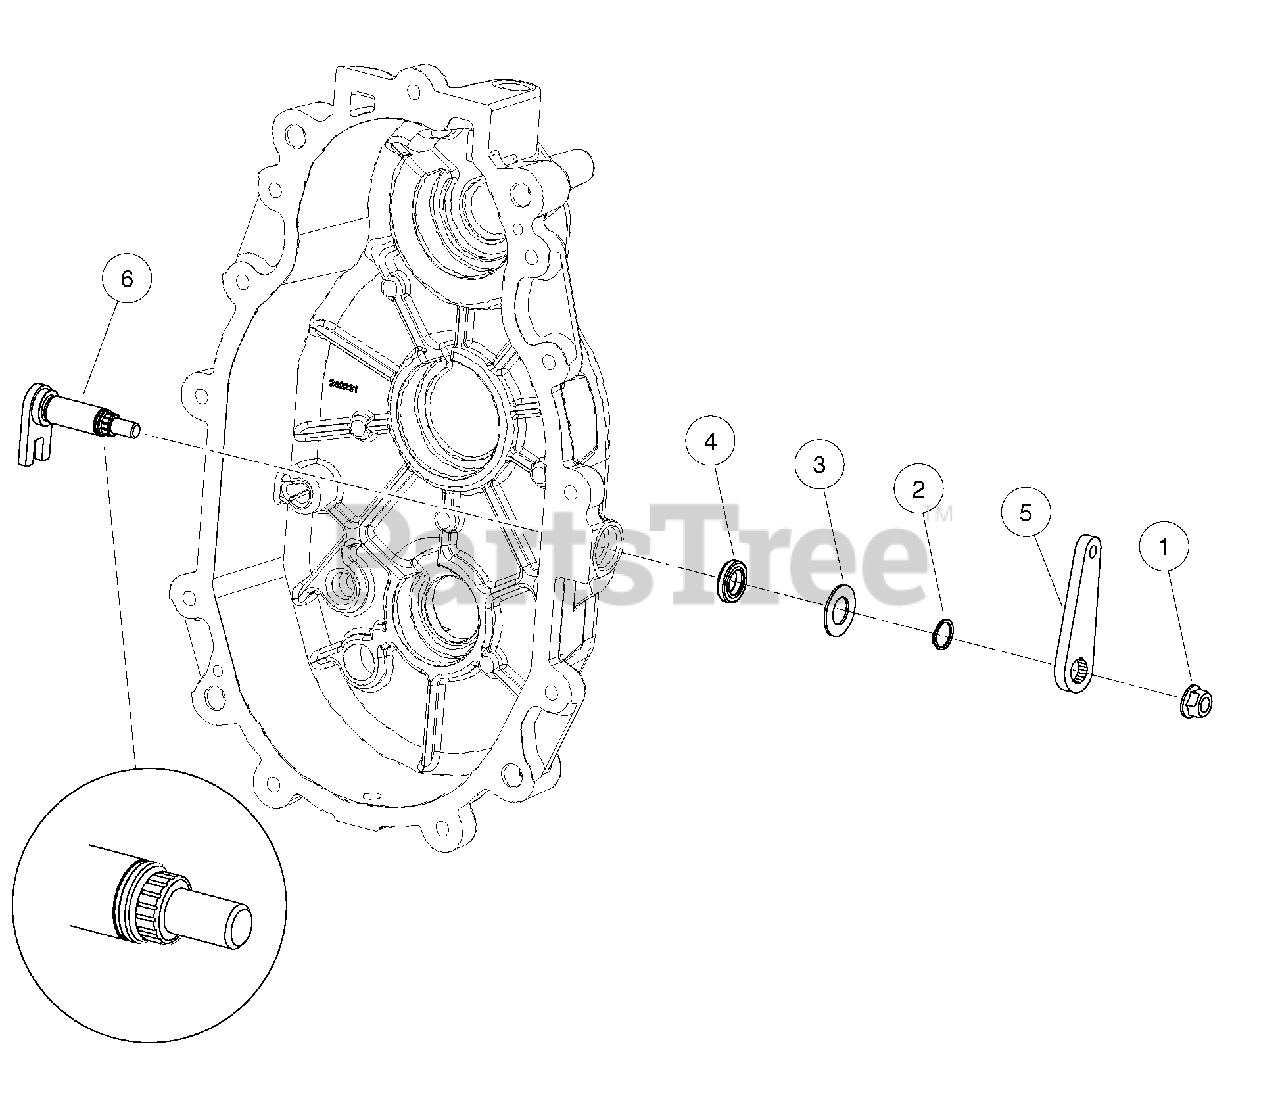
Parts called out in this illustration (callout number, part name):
1	Nut, Lock Hex, Nylon, 5/16-24
2	Ring, Retaining, External 9/16
3	Washer, Flat, .58 X 1.08 X .05
4	Seal, Dul Lip, .88 X .56 X .19
5	Bellcrank, Alum
6	Shaft, Shift
